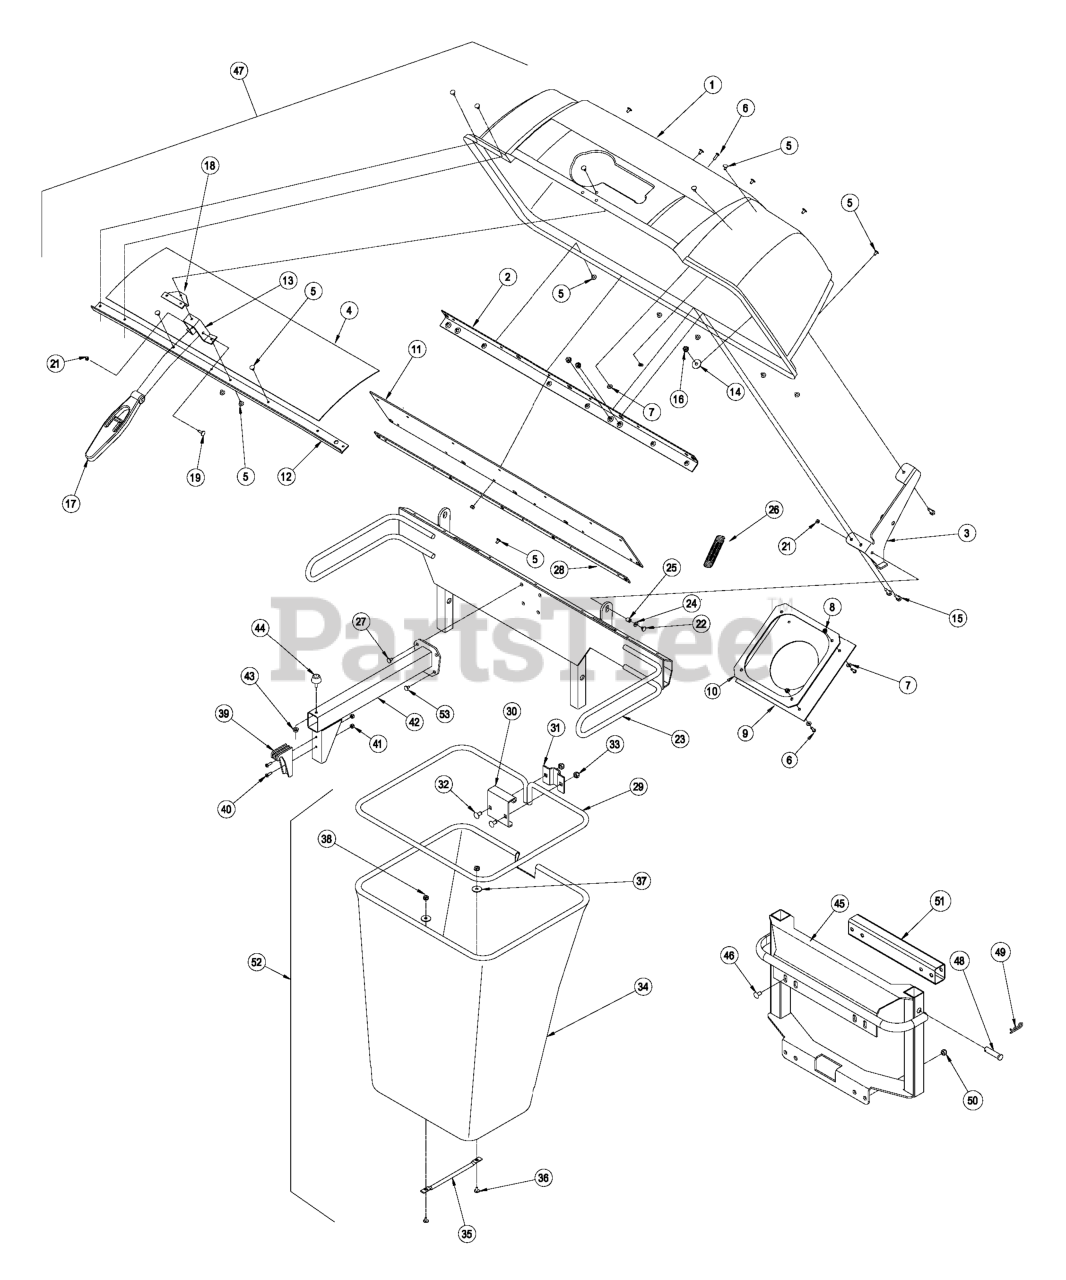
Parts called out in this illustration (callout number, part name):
2	STIFFENER-BAGGER, TOP
3	HINGE ASM
4	SCREEN-BAGGER
5	RIVET-BLIND
6	SCREW-HEAD, TRUSS
7	WASHER-FLAT
8	NUT-LOCK, NI
9	SEAL-CHUTE
10	CLAMP-SEAL
12	SUPPORT-SCREEN
13	ANCHOR-LATCH
15	SCREW-HH
18	REINFORCEMENT-LATCH
19	SCREW-HH
21	NUT-LOCK, NI
22	SCREW-HH
24	WASHER-FLAT
26	SPRING-EXTENSION
27	SCREW-HH
28	PLATE-BACKING
29	FRAME-BAG
30	HANGER-BAG
32	BOLT-CARR
33	NUT-LOCK, NI
35	HANDLE-BAG
36	BOLT-CARR
38	NUT-LOCK, NI
40	SCREW-PPH
45	BAGGER MOUNT ASM
46	SCREW-HH
47	ASM, HOOD
48	PIN-CLEVIS
49	PIN-COTTER
51	TUBE,SPACER
53	SCREW-HSBH
